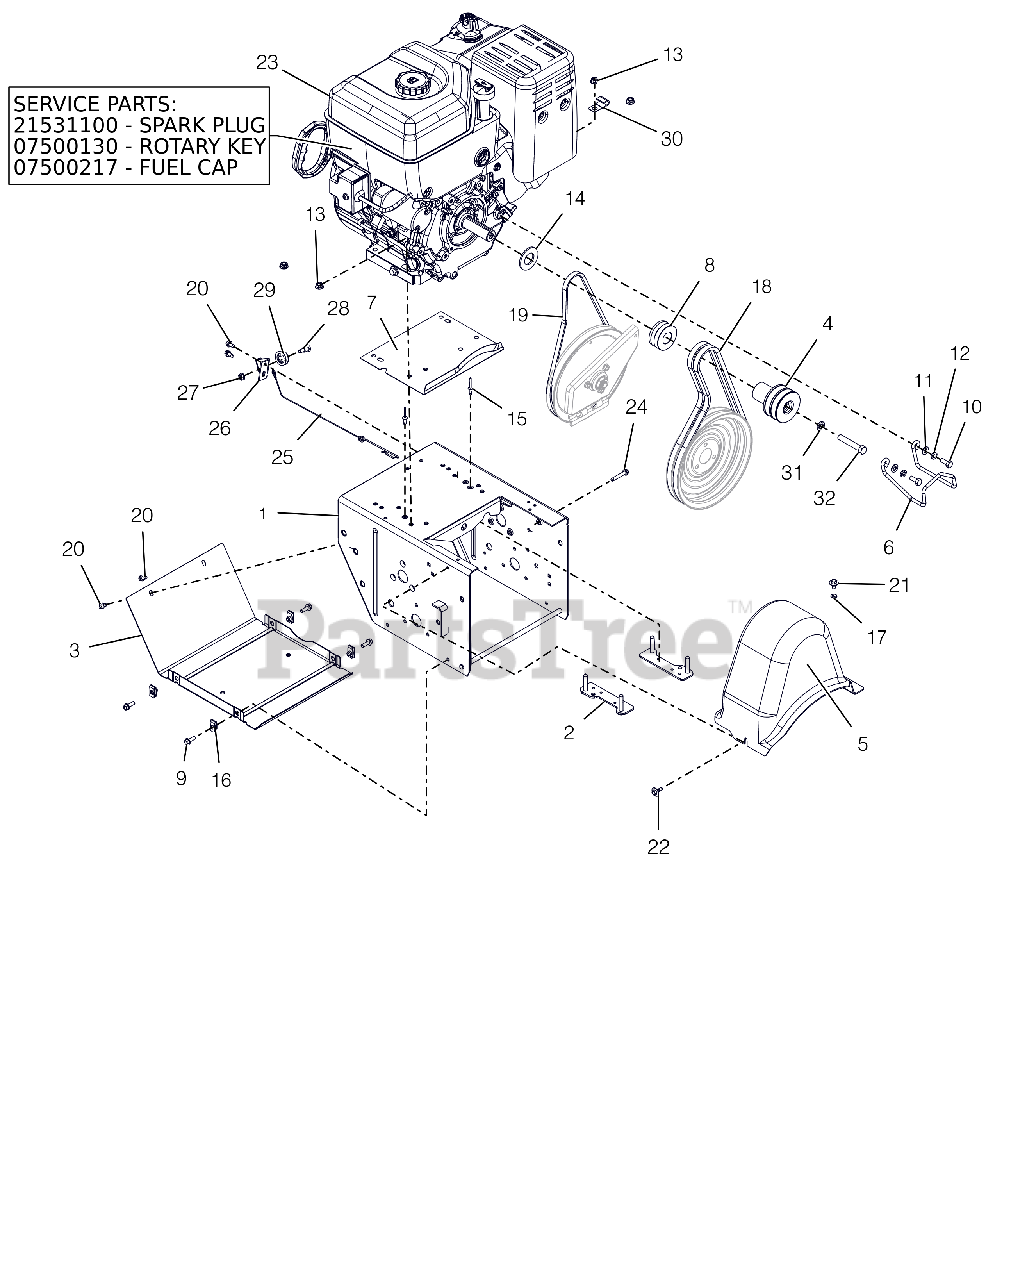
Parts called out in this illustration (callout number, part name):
1	FRAME, MAIN - PRO (WELDMENT)
2	STRAP, BOLT-LARGE
3	COVER, BOTTOM
4	SHEAVE, ATTACHMENT 2-GRV
5	COVER, BELT-LARGE
6	FINGER, BELT
7	BAFFLE, WATER - LARGE BLOCK
8	SHEAVE, DRIVE
9	BLT-HEX .25-20X.75 HWH YZ GR5
10	BLT-HEX .31-24X.75 YWZC GR5
11	@WSHR-FL-STL.344X.688X.065YWZC
12	WSHR-LK .312X.097 HVY YWZC
13	@NUT-LK-CTR-FLG .31-18 YZ GR F
14	WSHR-FL-STL- 1.062X2.0X.134 YZ
15	RVT-POP .187 YZ
16	NUT-RTNR .25-20X.56
17	NUT-PUSH .25X.50 O.D.
18	V-BELT, HA-RAW EDGE (SET)
19	V-BELT, 3L-WRAPPED
20	SCR-TAP .25-20X.50 HWH TR YWZ
21	SCR-TAP .25-20X.50 LGHWH TR YZ
22	SCR-TAP .25-20X.5 CAPTIVE
23	ENGINE, BRIGGS PF 2100, 120V
23	PLUG, SPARK 20HP B&S VANGUARD
23	KEY, IGNITION ROTARY B&S
23	CAP, FUEL - BRIGGS & STRATTON
24	@SCR-TAP .25-20X1.50 HWH TR YZ
25	CABLE, LOWER TRACTION,SS & PRO
26	BRACKET, CABLE PULLEY
27	@NUT-LK-TOP-FLG .25-20 YWZC
28	BOLT, SHLDR-.375X.375X.25-20
29	PULLEY, CABLE
30	J-CLAMP
31	@WSHR-LK .44X.109 REG YWZC
32	BLT-HEX .44-20X2.50 GR5 YWZC
